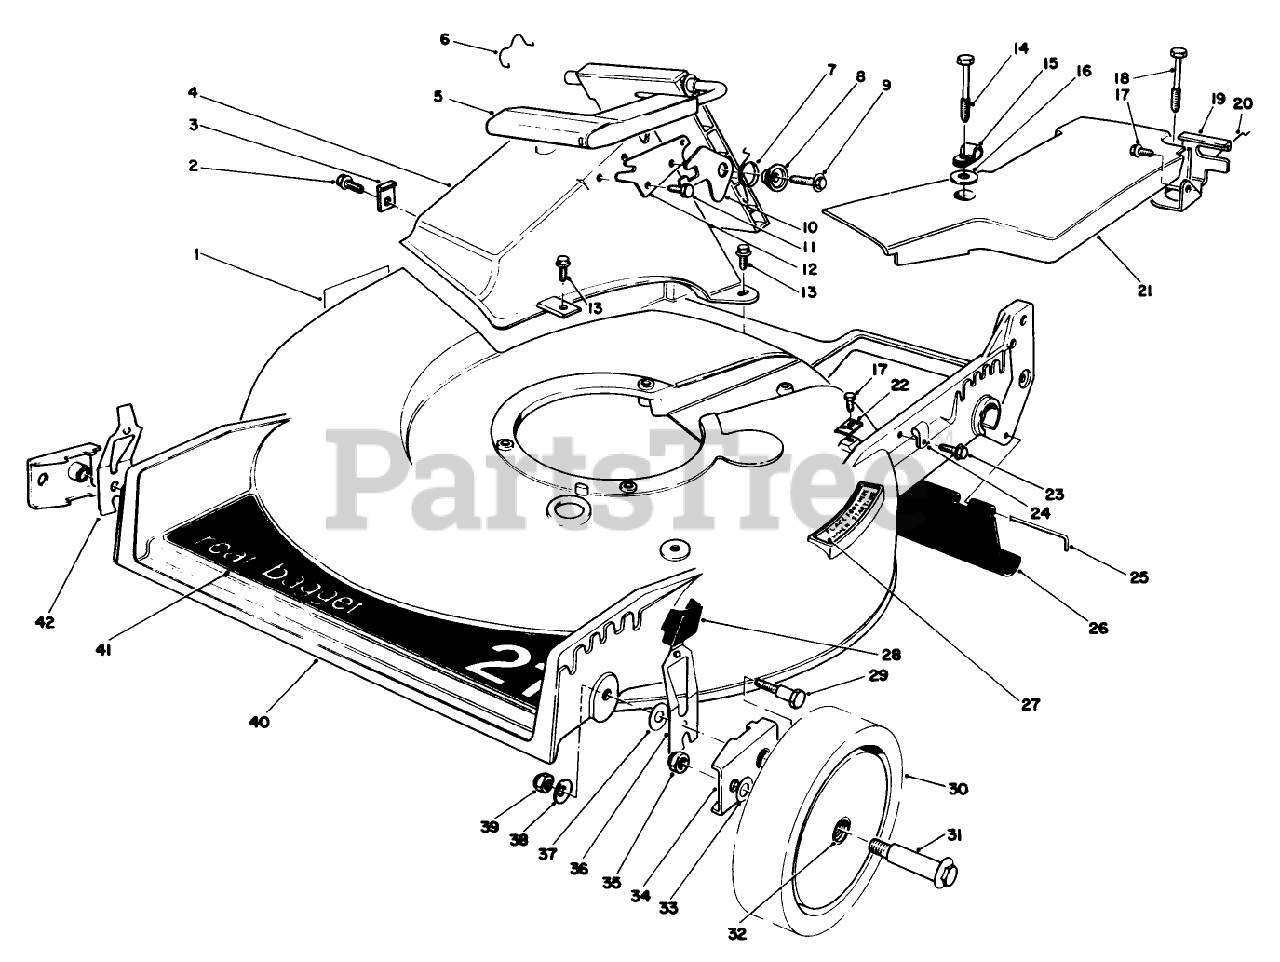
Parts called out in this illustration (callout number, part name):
1	DECAL-DANGER
2	SCREW
3	TUNNEL CLIP
6	DOOR RET SPRING
7	TORSION SPRING
8	DOOR SPACER
9	SCREW-HWH
10	SAFETY LATCH
11	SCREW-PLASTITE
12	DOOR LATCH PLATE
13	SCREW-HWH
14	SCREW-SPECIAL
15	CLAMP-CABLE
16	WASHER
17	SCREW-THD ROLL, HWH
18	SCREW-HWH
20	RETAINER-CABLE
23	SCREW
24	CLAMP-CABLE
25	ROD-SHIELD
27	STEP PAD DECAL
28	KNOB-ARM
29	PIVOT SCREW
31	BOLT-WHEEL
32	BUSHING
33	WASHER
34	HP PIVOT ARM ASM
37	WASHER-PIVOT
38	WASHER-BELLEVILLE
39	NUT-LOCK, NI
